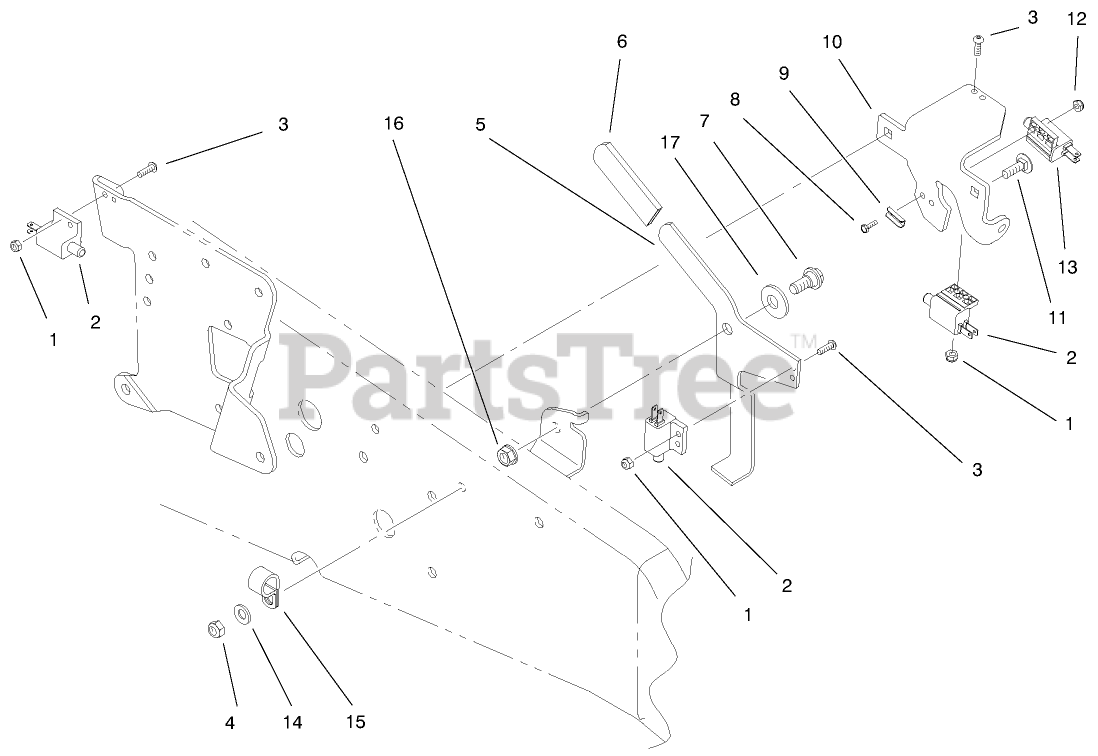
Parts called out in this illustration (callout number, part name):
1	NUT-LOCK, NI
3	SCREW-HSH
4	NUT-LOCK, NI
5	LATCH-BRAKE, PARKING
7	BOLT-SHOULDER
8	SCREW-SHH
9	RETAINER-SCREW
10	BRACKET-SWITCH
11	SCREW-CARR
12	NUT-LOCK
13	SWITCH-POLE, SINGLE
14	WASHER-PLAIN
15	CLAMP - R
16	NUT-HEX
17	WASHER
